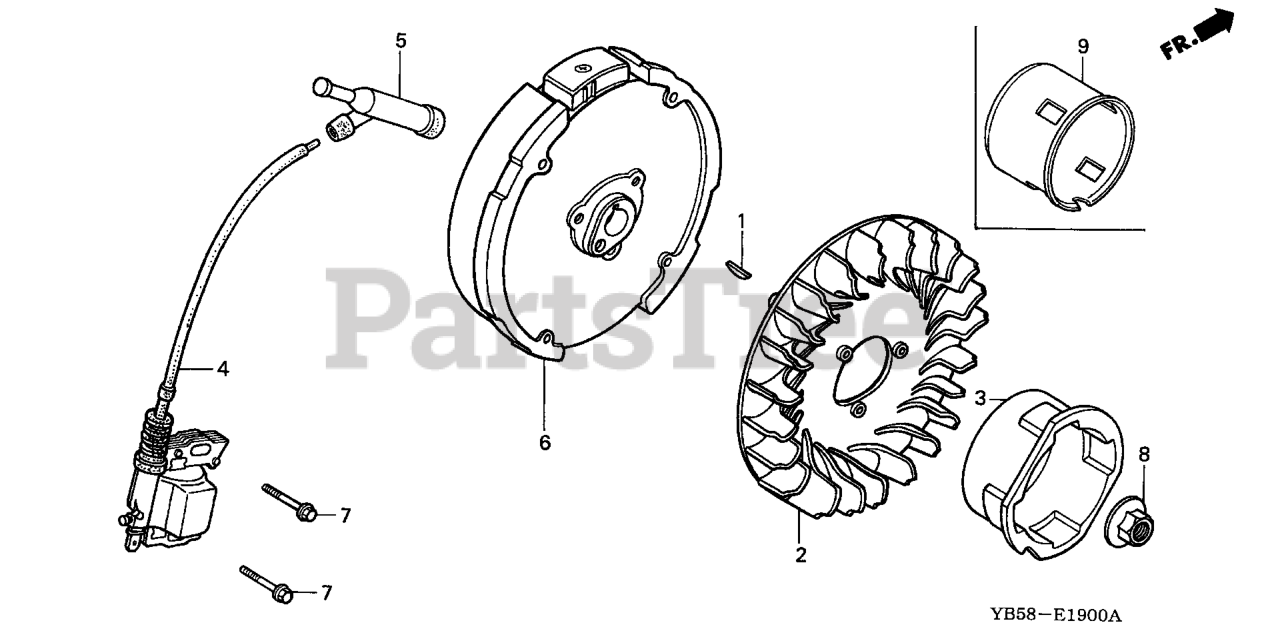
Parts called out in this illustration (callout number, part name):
1	KEY, SPECIAL WOODRUFF (25X18)
2	FAN, COOLING
4	COIL ASSY., IGNITION Use up to Engine SN 1530314.
5	CAP ASSY., NOISE SUPPRESSOR (Honda Code 3526837). (NICHIWA Y-EZ RTFM256)
6	FLYWHEEL
7	BOLT, FLANGE (6X25) Use up to Engine SN 2056819.
8	NUT, SPECIAL (14MM)
9	PULLEY, STARTER
